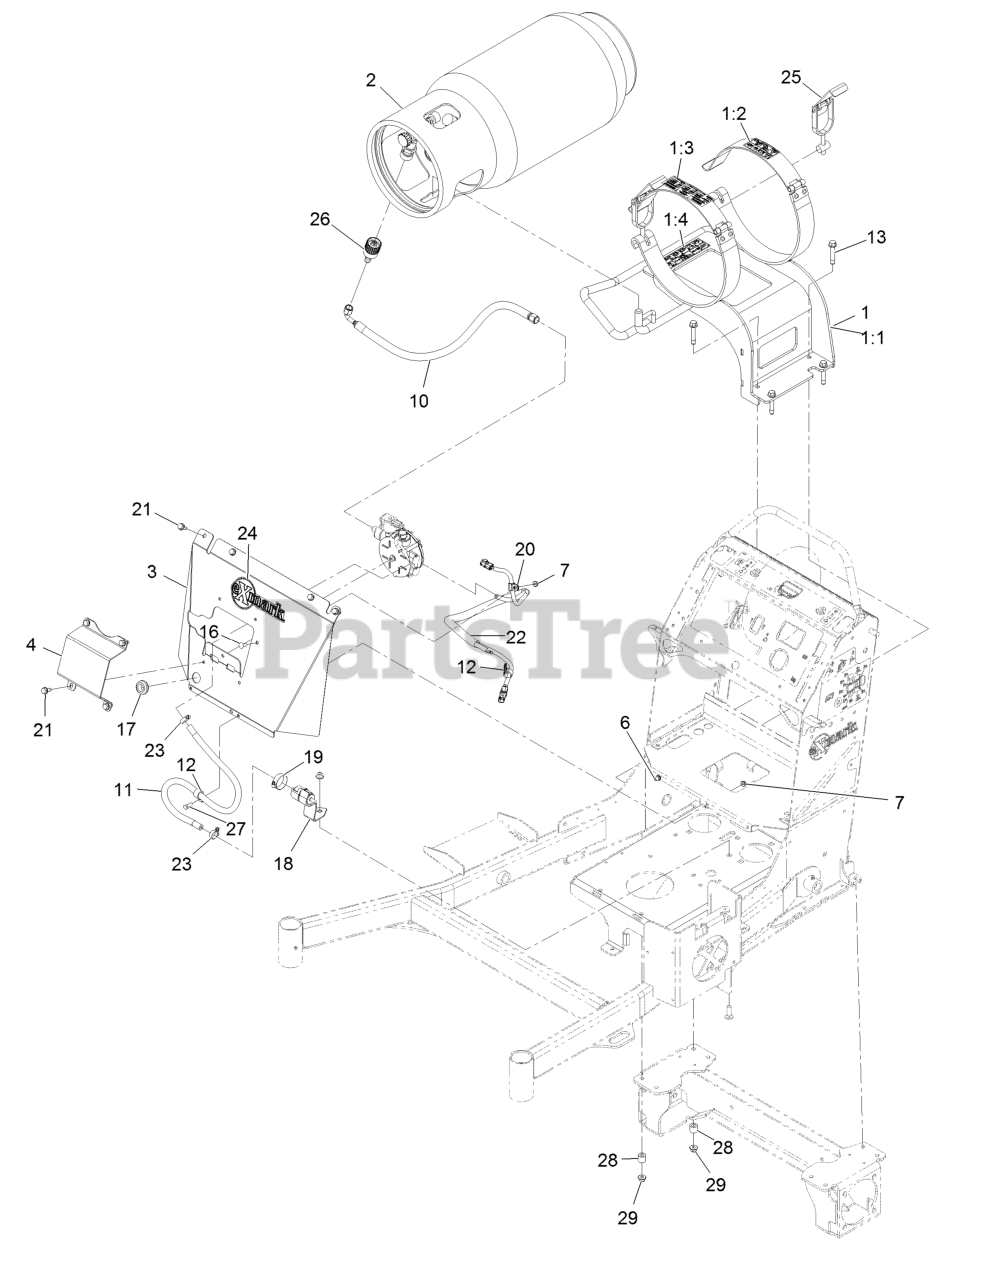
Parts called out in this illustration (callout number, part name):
1	ASM, LP Tank Mount W/Decal
1:1	Bracket-LPG Tank [black]
1:2	Decal-LPG Warning
1:3	Decal-LPG Horiz Tank Spec
1:4	Decal-LPG Fuel Tank Replacement
2	Tank, LP - 33.5 Lb.Horizontal-Al
3	Panel, Front
4	Guard, Regulator
6	Bolt-Carriage 1/4-20 X 3/4
7	Nut-Nyloc 1/4-20 Flg
10	ASM-Hose, LPG
11	Hose, Fuel
12	Clamp-Cable
13	Screw-HHF W/ Patch
16	Screw-CARR
17	Grommet
18	Bracket, Filter
19	Clamp-Hose
20	Clip-Loom
21	Screw-HWH 5/16-18 X 3/4 Tf
22	ASM, Vent Hose And Harness
23	Clamp-Hose
24	Decal, Exmark Logo
25	Latch, LP Tank
26	Connector-LP, Straight
27	Screw-HH 1/4-20 X 3/4
29	Nut-Nyloc 3/8-16 Flg
